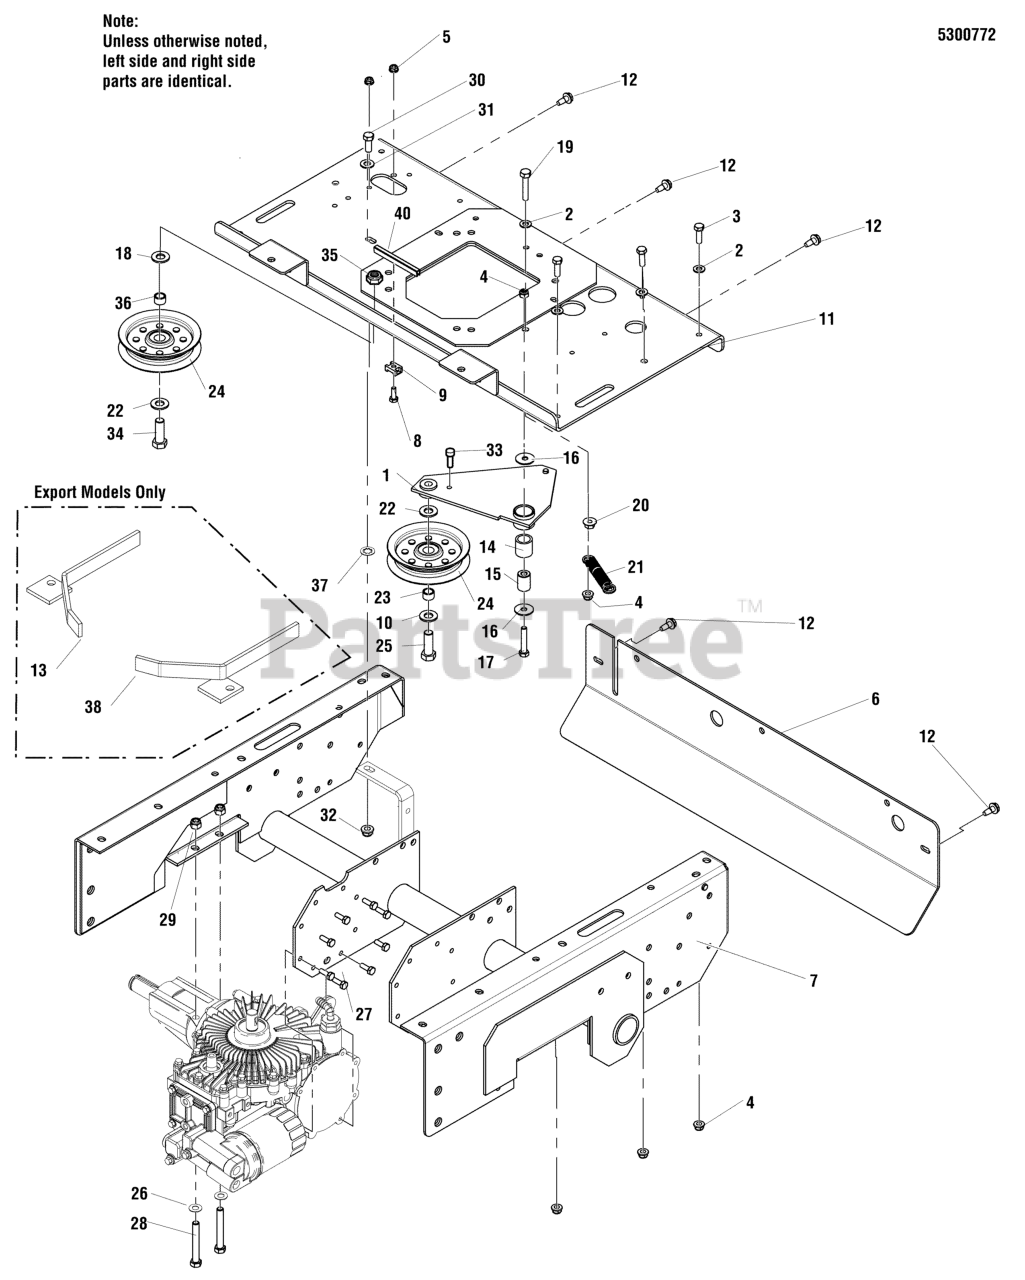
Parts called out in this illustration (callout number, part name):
1	WELD, MOUNT, GROUND DRIVE IDLER
2	WASHER, 5/16" SAE
3	BOLT, 5/16-18 X 1" GD5
4	NUT, 5/16-18 HEX NYLOCK FLANGE
5	NUT, 1/4-20 HEX SERR. FLANGE
6	PLATE, ENGINE DECK BACK
7	WELD, ENGINE DECK, DDS
8	BOLT, 1/4-20 X 3/4" GD5
9	CABLE TIE ANCHOR MOUNT
10	WASHER, LOCK, 1/2 HI-ALLOY CZ
12	BOLT, 5/16-18 X 3/4" SELF TAP
13	WELD, ENGINE, CE GUARD RH
14	BUSHING, BRASS 3/4 X 1 X 1
15	SPACER, .32 X .75 X 1.06
16	WASHER, 5/16" FENDER
18	WASHER, FRAME RETAINING
19	BOLT, 5/16-18 X 1-1/4" GD5
20	NUT, 5/16-18 HEX SERRATED FLANGE (LARGE)
21	SPRING, EXTENSION
22	WASHER, 1/2 SAE
23	INSERT, BEARING
24	PULLEY, IDLER
26	WASHER, 3/8 GR. 9
27	BOLT, 1/4-20 X 3/4" GD5 WITH PATCH
29	NUT, 3/8-16 HEX NYLON FLANGE
30	BOLT, 3/8-16 X 1" GD5 CZ
31	WASHER, 3/8 SAE
32	NUT, 3/8-16 HEX SER FLANGE
33	RIVET, PLASTIC PUSH-IN
34	BOLT, 1/2-20 X 2-1/4 GD5 CZ
35	NUT, Hex, Nylon Lock, 1/2-20
36	INSERT, BEARING 1/2" SHOULDER
37	3/8 PUSHNUT BOLT RETAINER
38	WELD, ENGINE, CE GUARD LH
39	GROMMET
40	BLACK SOFTONE Q-TRIM, 4.00" LONG
